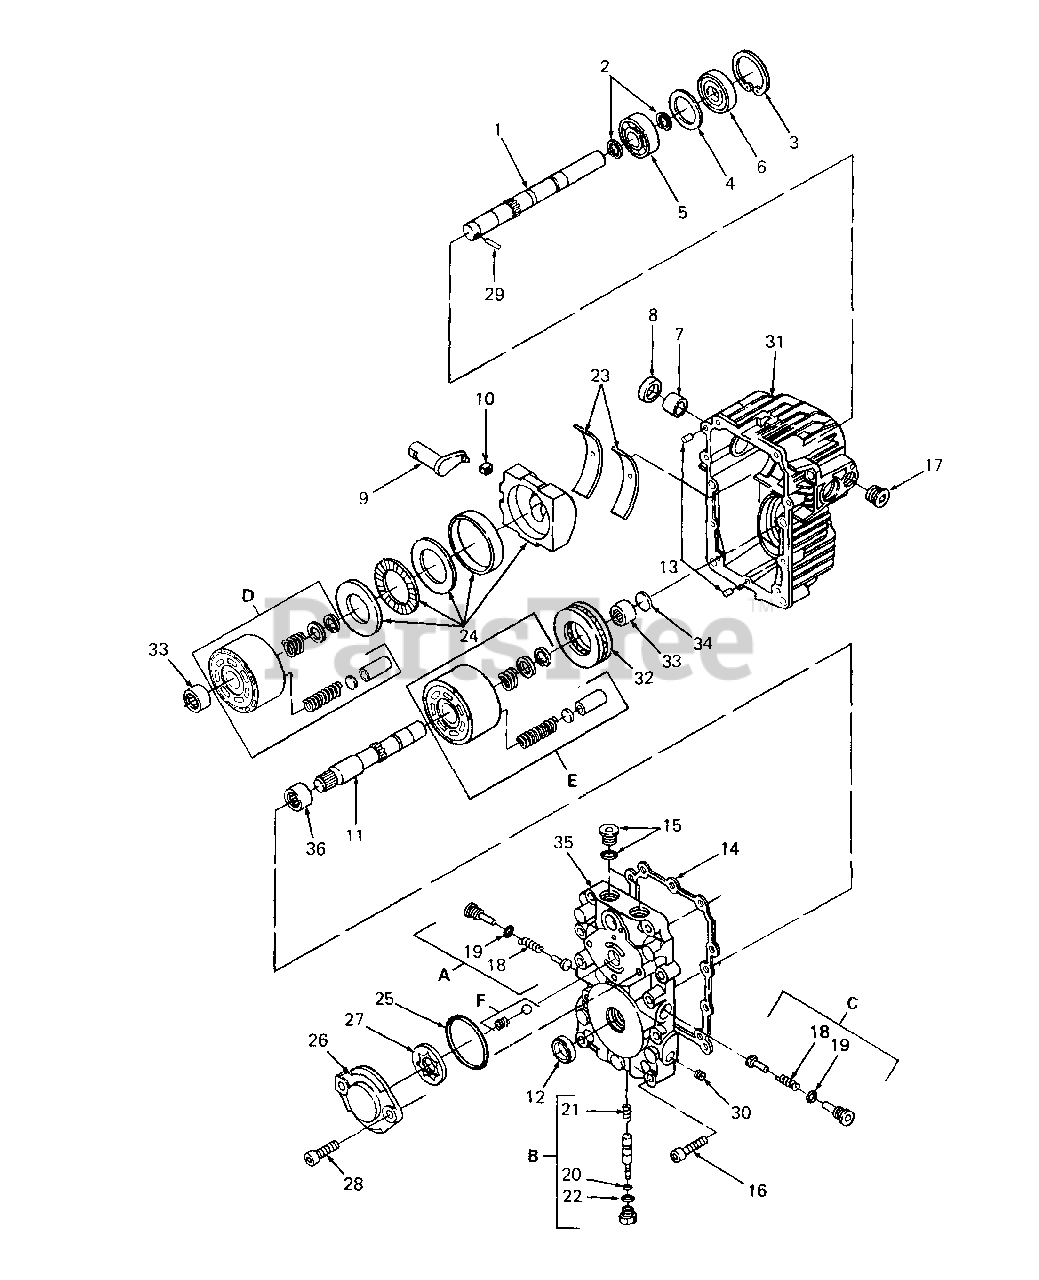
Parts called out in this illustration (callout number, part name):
1	Shaft, Pump
2	Ring, Retaining
3	Ring, Retaining
4	Spacer
5	Bearing, Ball
6	Seal, Lip
7	Bearing, Journal
8	Seal, Lip
9	Arm, Trunnion
10	Guide, Slot
11	Shaft, Motor
14	Gasket, Center Section
19	O-Ring
20	O-Ring
21	Spring
22	O-Ring
23	Bearing, Cradle
26	Housing, Charge Pump
27	Gerotor Assy
31	Housing Assy
32	Bearing, Thrust Ball
33	Bearing, Needle
34	Washer, Thrust
35	Center Section Assy
36	Bearing, Needle
A	Kit, Poppet Check Valve
B	Kit, Bypass Valve
C	Kit, Orificed Check Valve
D	Kit, Pump Cylinder Block
E	Kit, Motor Cylinder Block
F	Kit, Charge Relief Valve
